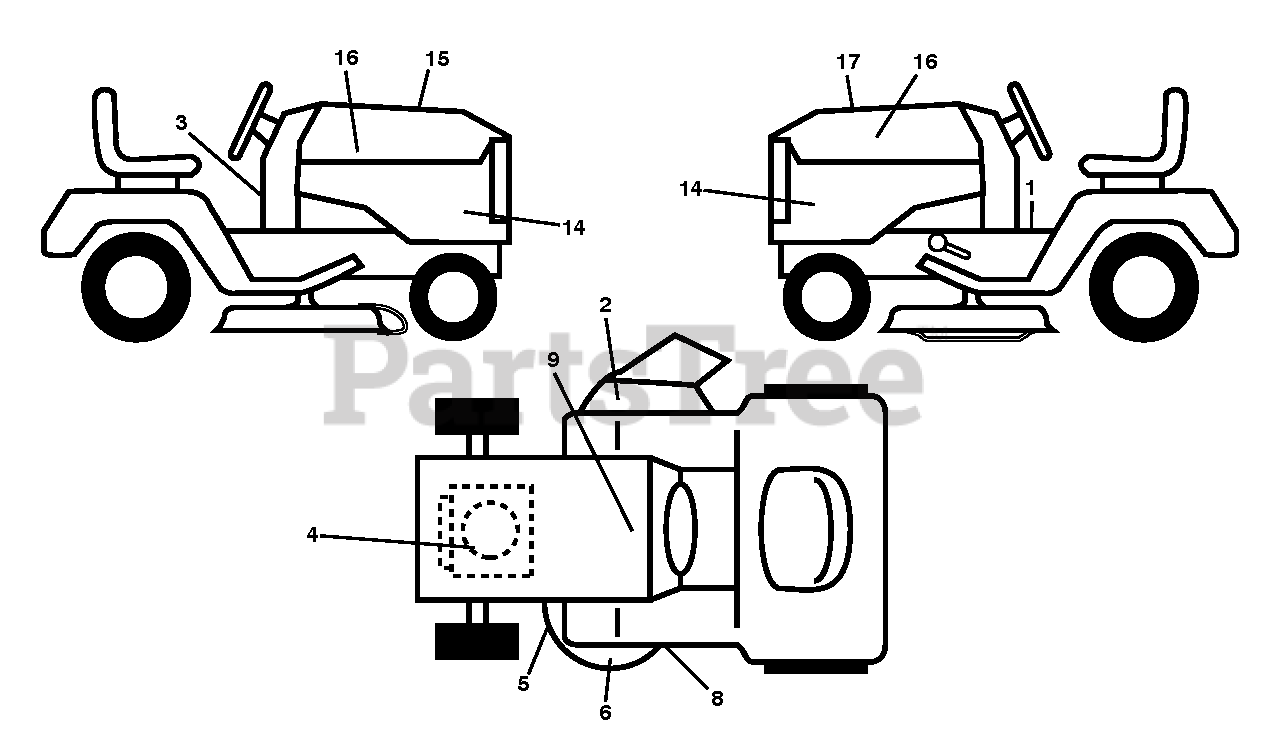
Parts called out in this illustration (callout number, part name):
1	DECAL.FENDER.WARNING.ENGLISH
2	DECAL.MOWER.WARN.KEEP.HAND.AWY
3	DECAL.SNOWFLAKE.MS498.HUSQ
4	DECAL.ENG.BS.INTK.24HP.382016
5	DECAL.MOWER.CAUTION.TENSION.AR
8	DECAL.MOWER.SCH.48/54.PREM
9	DECAL BTRY SYMBOLS
14	DECAL SIDE PANEL
15	DECAL.WARNING.CUST.RESP.E85.
16	DECAL.BADGE.170MM.TEXTLOGO.
17	DECAL.RPL.BSM44.INTK.TLW.48
